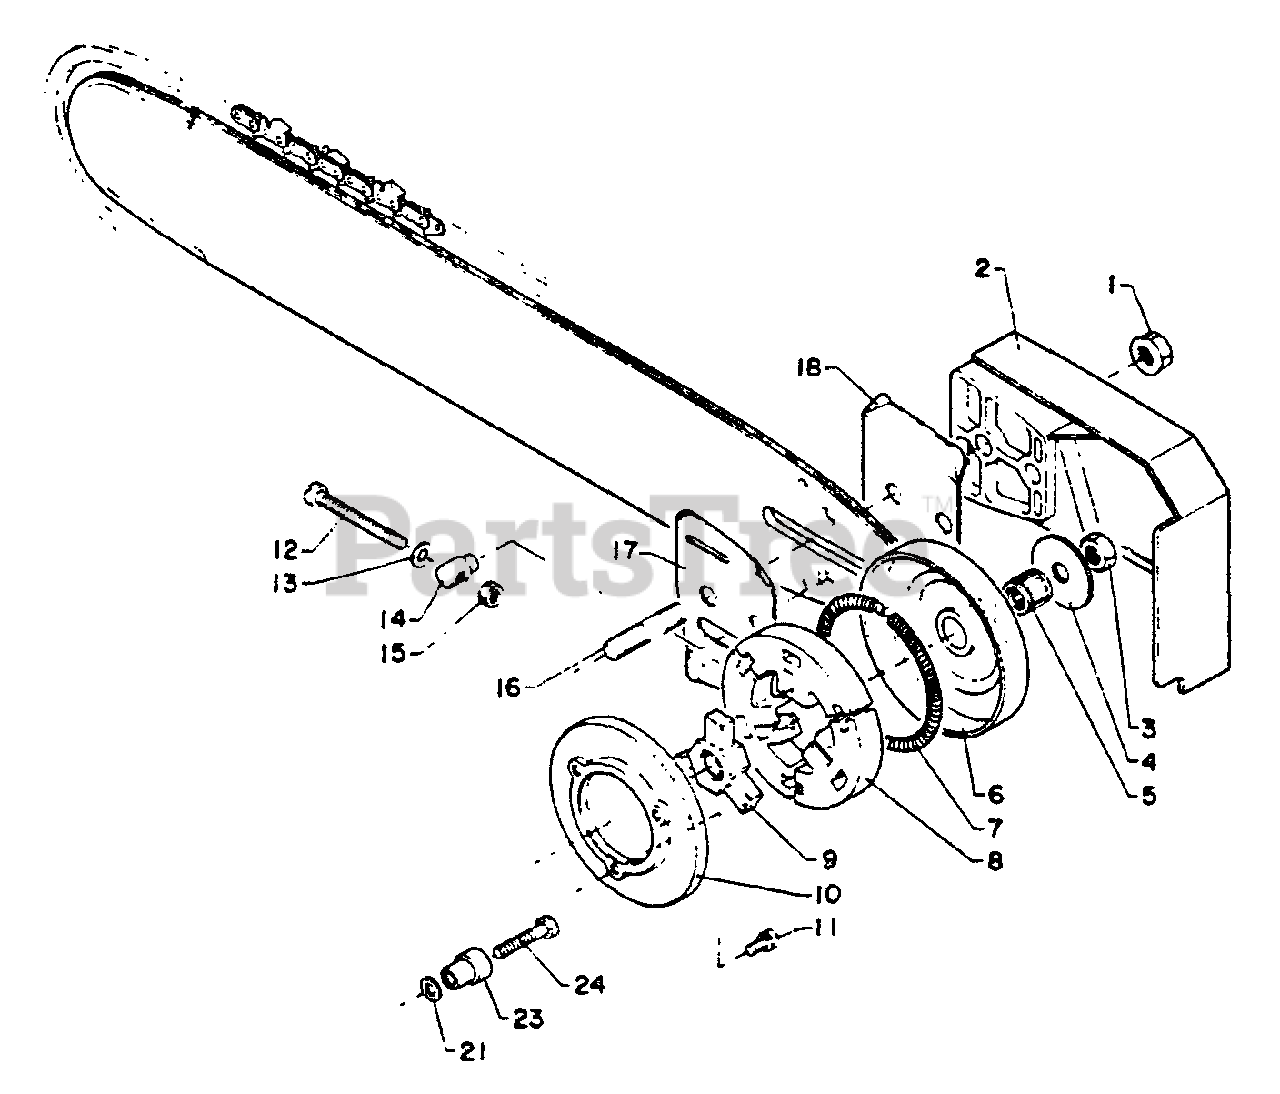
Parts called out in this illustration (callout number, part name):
1	NUT - FLANGE
2	GUARD, SPROCKET
3	LOCKNUT
4	WASHER, CLUTCH
5	BEARING, NEEDLE
6	DRUM, CLUTCH
7	SPRING, CLUTCH
8	SHOE, CLUTCH
9	HUB, CLUTCH
10	SEAL, DUST
11	SCREW - 4X10
12	SCREW, TENSIONER
13	WASHER - 5
14	TENSIONER, CHAIN
15	LOCKNUT - 5
16	STUD, GUIDE BAR
17	PLATE, GUIDE - INNER
18	PLATE, GUIDE - OUTER
21	WASHER - 5
23	CATCHER, CHAIN
24	SCREW - 5X25
